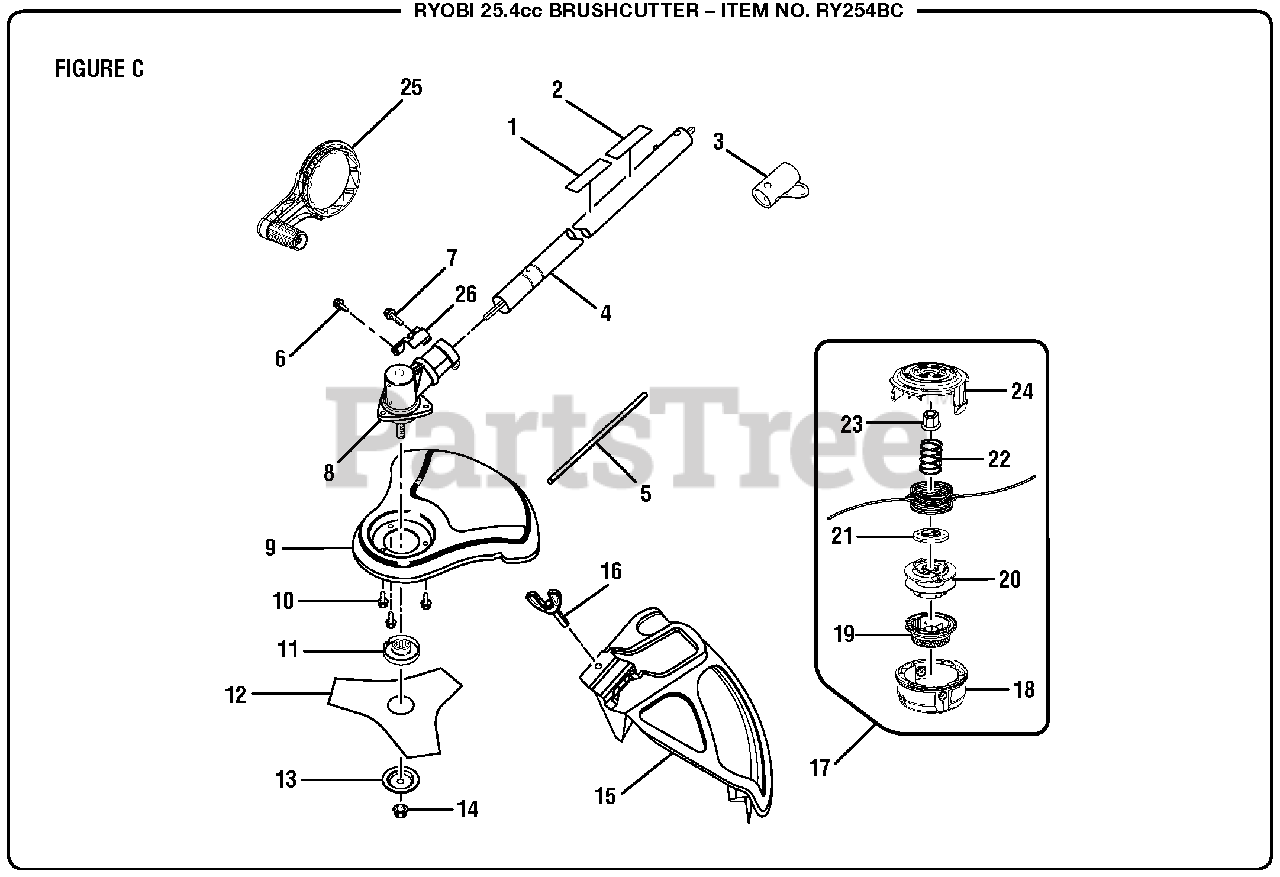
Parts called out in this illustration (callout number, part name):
1	Expand-It Logo Label
2	Brushcutter Safety Label
3	Storage Hanger Cap
4	Lower Straight Shaft Boom Assembly
5	Gear Head Locking Tool
6	Screw (1/4-20 x 1-1/4 in., Hex Washer Hd. S.T.)
7	Screw (10-24 x 5/8 in., Hex Washer Hd. S.T.)
8	Gear Case Assembly
9	Brushcutter Guard
10	Screw w/Washer (10-24 x 1/2 in., Slotted Hex Hd.)
11	Flanged Washer
13	Cupped Washer
14	Lock Nut (M8 x 1.25 in., Left Hand Threads)
15	Grass Deflector Assembly
16	Screw (1/4-20 x 7/8 in.)
17	Trimmer Head Assembly (.095)
18	Lower Housing
19	Bump Knob (Green)
21	String Guide
22	Compression Spring
23	Hex Nut (M8, L.H. Thread)
24	Upper Housing
25	Crank Handle Assembly
26	String Guard Clamp
